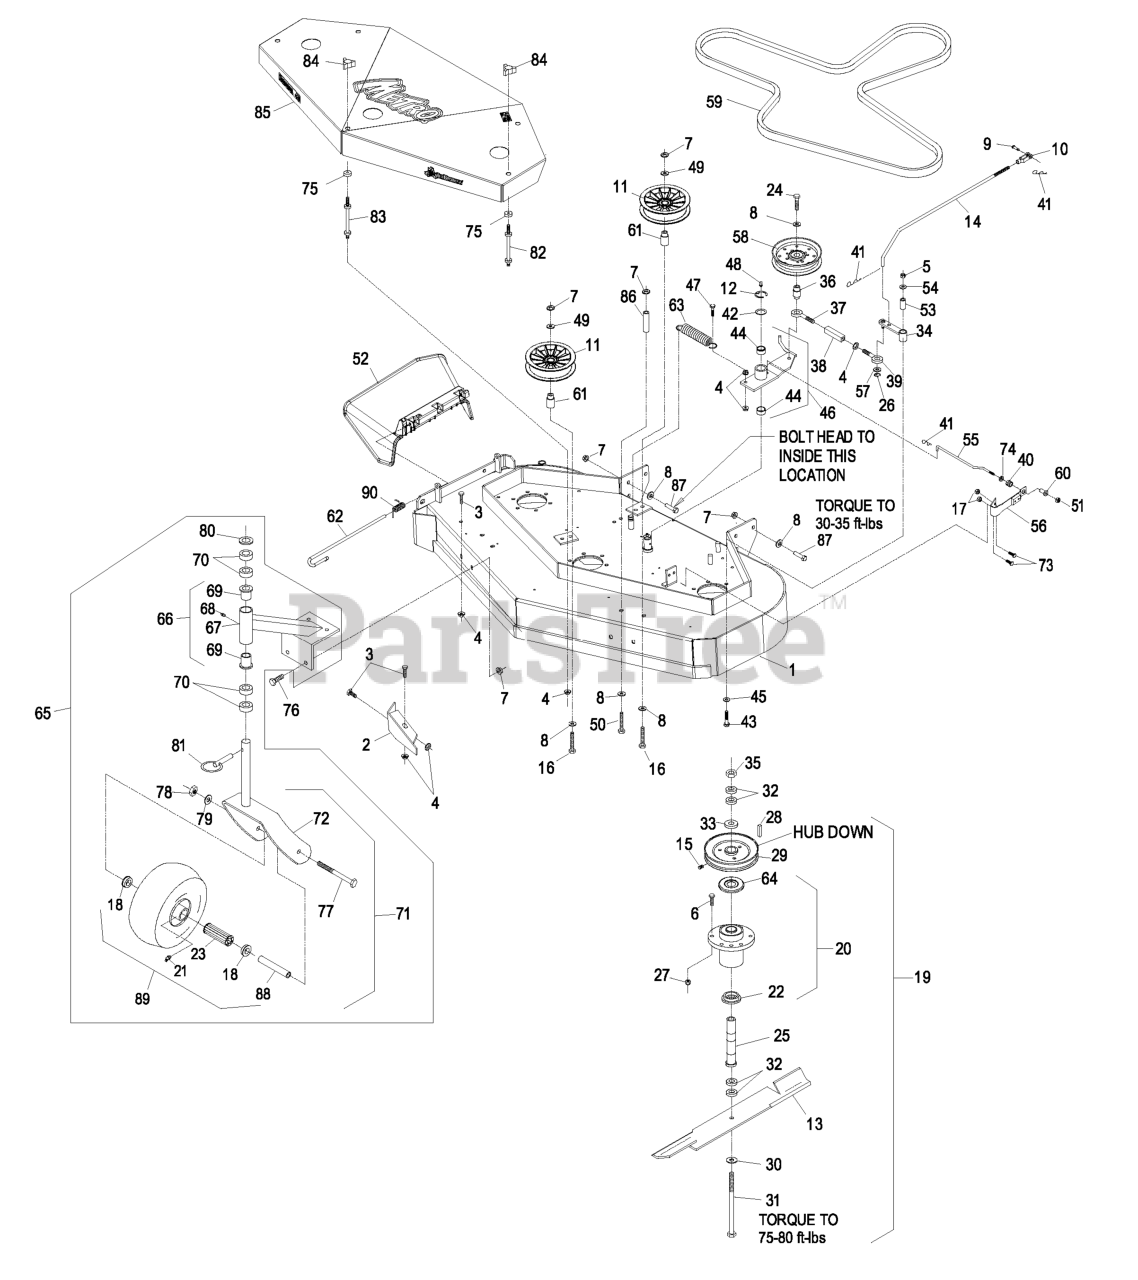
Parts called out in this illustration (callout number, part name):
2	BAFFLE-DOGLEG
3	SCREW-HH
5	NUT-LOCK, NI
6	SCREW-HH
7	NUT-HHF, WHIZ
8	WASHER-BELLEVILLE
9	PIN-CLEVIS
10	YOKE-ADJUSTABLE
11	PULLEY,IDLER 5"
12	RING-RETAINING, EXT
14	ARM-ASSIST, LINKAGE
15	SCREW-SET
16	SCREW-HH
17	NUT-LOCK, NI
18	BUSHING
19	ASM, CUTTER HOUSING OUTER
20	KIT, CUTTER HOUSING
21	FITTING-GREASE
22	SPACER-GUARD, BOTTOM
23	BEARING
24	SCREW-HH
25	TUBE-SPINDLE, SHORT
26	RING-RETAINING, EXT
27	NUT-LOCK, NI
29	SHEAVE
30	WASHER-SPRING
31	SCREW-CAP, HH
33	WASHER-RETAINER, SHEAVE
34	ARM-ASSIST, 32/36
35	NUT-HEX
36	BUSHING-ENGAGEMENT
37	EYEBOLT-THREAD, LH
38	BODY-TURNBUCKLE
39	EYEBOLT-THREAD, RH
40	SPRING-COMPRESSION
41	PIN-COTTER
42	WASHER-SPINDLE
43	SCREW-HH
44	SLEEVE-BEARING
45	WASHER-SPRING
46	IDLER ARM ASM
47	SCREW-HH
48	FITTING-GREASE
49	WASHER-FLAT
50	SCREW-HH
51	NUT-LOCK, NI
52	CHUTE DEFLECTOR XRK M056
53	TUBE-PIVOT
54	WASHER-FLAT
55	ROD-BRAKE
56	PAD AND SPRING ASM
57	WASHER-PLAIN
59	BELT,BLADE 48
60	SPACER-FLANGED
61	BUSHING-IDLER
62	PIN-CHUTE
63	SPRING-EXTENSION
64	GUARD-BEARING, TOP
65	ASM,CASTER/MOUNT
66	SUPPORT ASM
68	FITTING-GREASE
69	BEARING-FLANGED
70	SPACER-CASTER
71	ASM,CASTER/WHEEL
73	SCREW-HH
74	RING-PUSH ON
76	SCREW-HH
77	SCREW-HH
78	NUT-HH
79	WASHER-LOCK
80	WASHER-FLAT
82	STUD-SHIELD, BELT (SHORT)
83	STUD-SHIELD, BELT (LONG)
84	KNOB-3 PRONG
85	ASM,SHIELD W/DECALS 48 ME
87	SCREW-HH
89	KIT, SP CASTER WHEEL REPL
90	SPRING, TORSION
